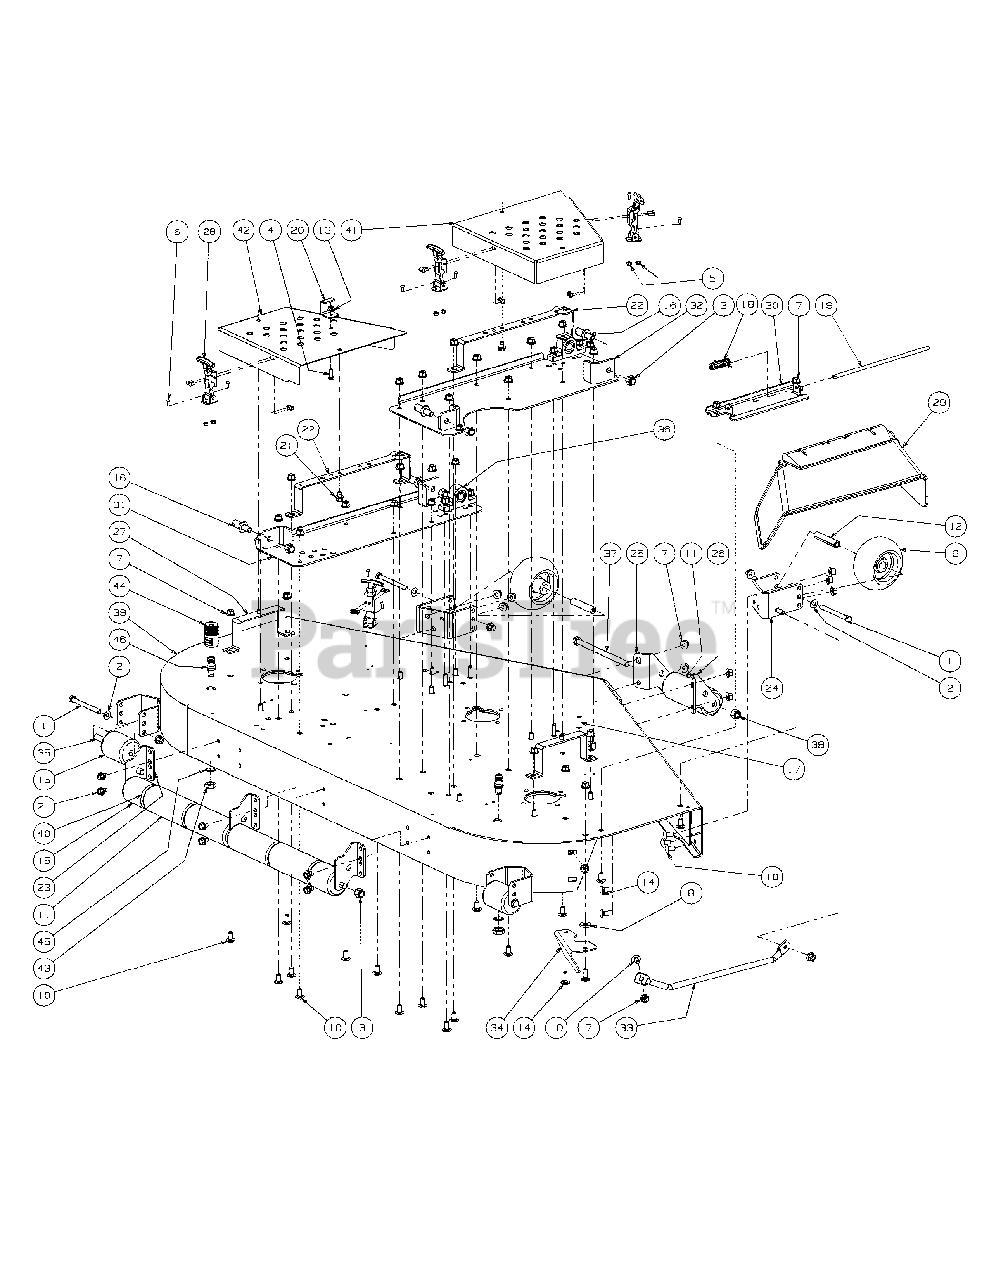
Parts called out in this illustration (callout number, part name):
1	Hex Cap Screw, 3/8-16, 3.75
2	Flat Washer, 3/8
3	Lock Nut, Nylon Insert, 1/2-13
4	Hex Cap Screw, 5/16-18 x .75
5	Lock Nut, Nylon Insert, 10-32
6	Phillips Head Screw, 10-32
7	Flange Lock Hex Nut, 3/8-16
8	Idler Washer
9	Complete Wheel, 5.00 Dia.
10	Carriage Bolt, 3/8-16 x .75 Lg.
11	Front Roller
12	Wheel Spacer
13	Nut, 5/16-18, Hex Flange Lock
14	Carriage Bolt, 3/8-16 x 1
15	Grass Catcher Roller
16	Pin, 5/8 Dia. x 1.2 Lg.
17	Carriage Screw, 3/8-16 x 1.25
18	Torsion Spring, 0.4ID x 2.16Lg
19	Chute Deflector Rod
20	Stop Bracket
21	Hex Index Washer Screw, 3/8-16, .5
22	Belt Cover Support
23	Deck Roller Mount Bracket
24	Anti-Scalp Wheel Front Mount Bracket
27	Outer Belt Cover Support Assembly
28	T-Handle Latch Draw
29	Chute Deflector
30	Chute Deflector Bracket
31	Left Hand Mount Deck Bracket Assembly
32	Right Hand Deck Bracket Assembly
33	Finger Guard
34	Chute Bracket
35	Spacer, .385 x .50 x 3.045
36	Pillow Block
37	Hex Cap Screw, 1/2-20 x 7.50
38	Lock Nut, Nylon Insert, 1/2-20
39	60 Deck Assembly
40	J-Hook w/ Threaded Roller
41	Right Hand Deck Belt Cover
42	Left Hand Deck Belt Cover
43	Hex Nut, M16-1.5
44	Water Nozzle Adaptor
45	Lock Washer, 17 x 23.8 x 1.95
46	Deck Water Nozzle
